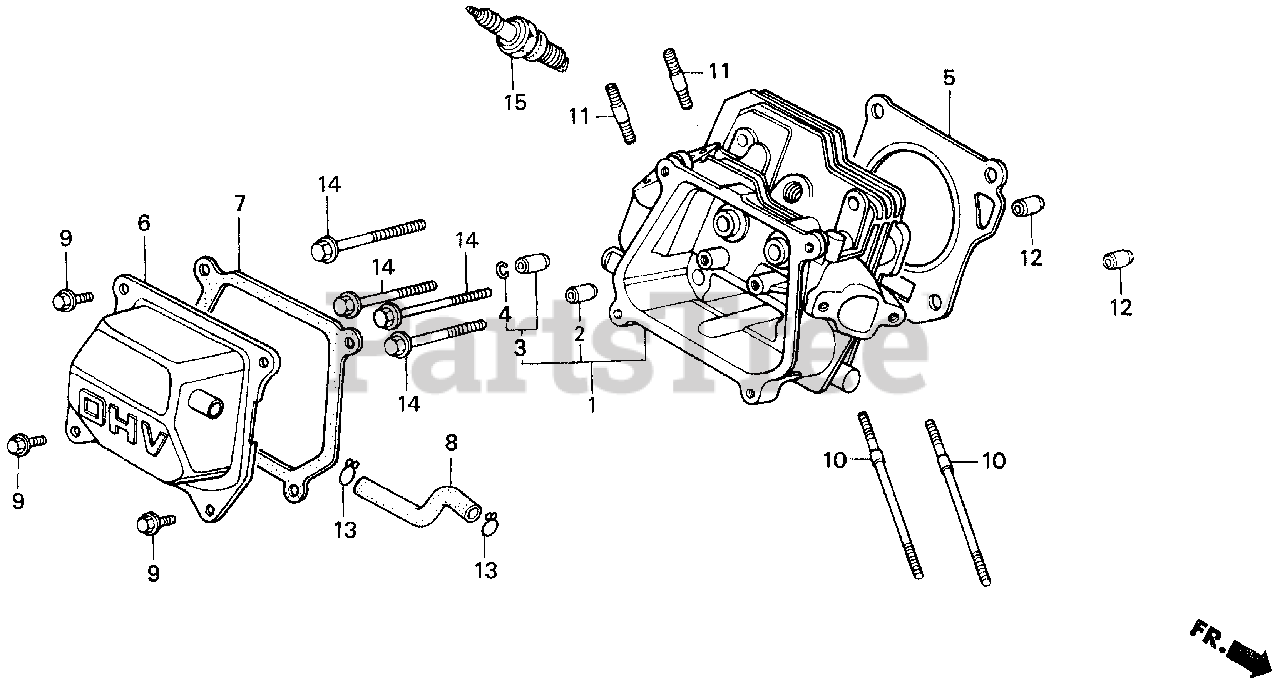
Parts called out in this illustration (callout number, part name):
1	CYLINDER HEAD
2	GUIDE, VALVE (OS)
3	GUIDE, EX. VALVE (OS)
4	CLIP, VALVE GUIDE
5	GASKET, CYLINDER HEAD
6	COVER, HEAD
7	GASKET, CYLINDER HEAD COVER
8	TUBE, BREATHER
9	BOLT, FLANGE (6X12) (CT200)
9	BOLT, FLANGE (6X13)
10	BOLT, STUD (6X109)
11	BOLT, STUD (8X32)
12	PIN A, DOWEL (10X16)
14	BOLT, FLANGE (8X55)
15	SPARK PLUG (BPR5ES) (NGK)
15	SPARK PLUG (W16EPR-U) (DENSO)
15	SPARK PLUG (BPR6ES) (NGK)
15	SPARK PLUG (W20EPR-U) (DENSO)
